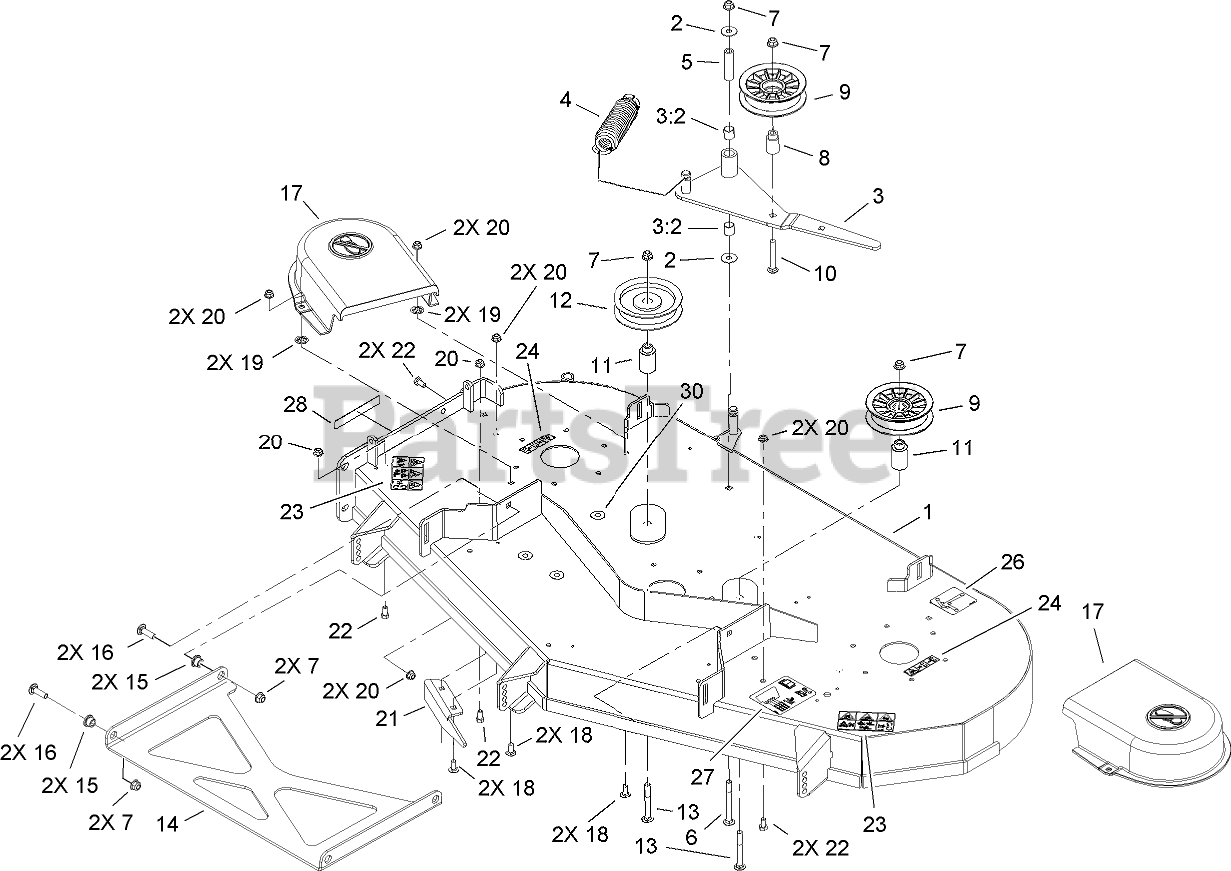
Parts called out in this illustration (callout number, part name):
1	52 INCH DECK ASM
2	WASHER
3	IDLER ARM ASM
3:2	SLEEVE-BEARING
4	Spring-Extension
5	BUSHING-PIVOT, IDLER
6	SCREW-CARR
7	NUT-HF, NI
8	BUSHING-IDLER
9	SHEAVE AND BEARING ASM
10	SCREW-CARR
11	BUSHING-IDLER
12	PULLEY-IDLER
13	BOLT-CARRIAGE
14	STRUT-DECK
15	SPACER-STRUT
16	SCREW-CARR
17	SHIELD-BELT
18	SCREW-CARR
19	RING-RETAINING
20	NUT-HF, NI
21	BAFFLE-DISCHARGE
22	SCREW-HH
23	DECAL-DANGER
24	DECAL-WARNING, BELT SHIELD
26	DECAL-BELT ROUTING
27	DECAL-ROLLER, ANTI-SCALP
28	DECAL-DANGER
30	DECAL-COVER, HOLE
